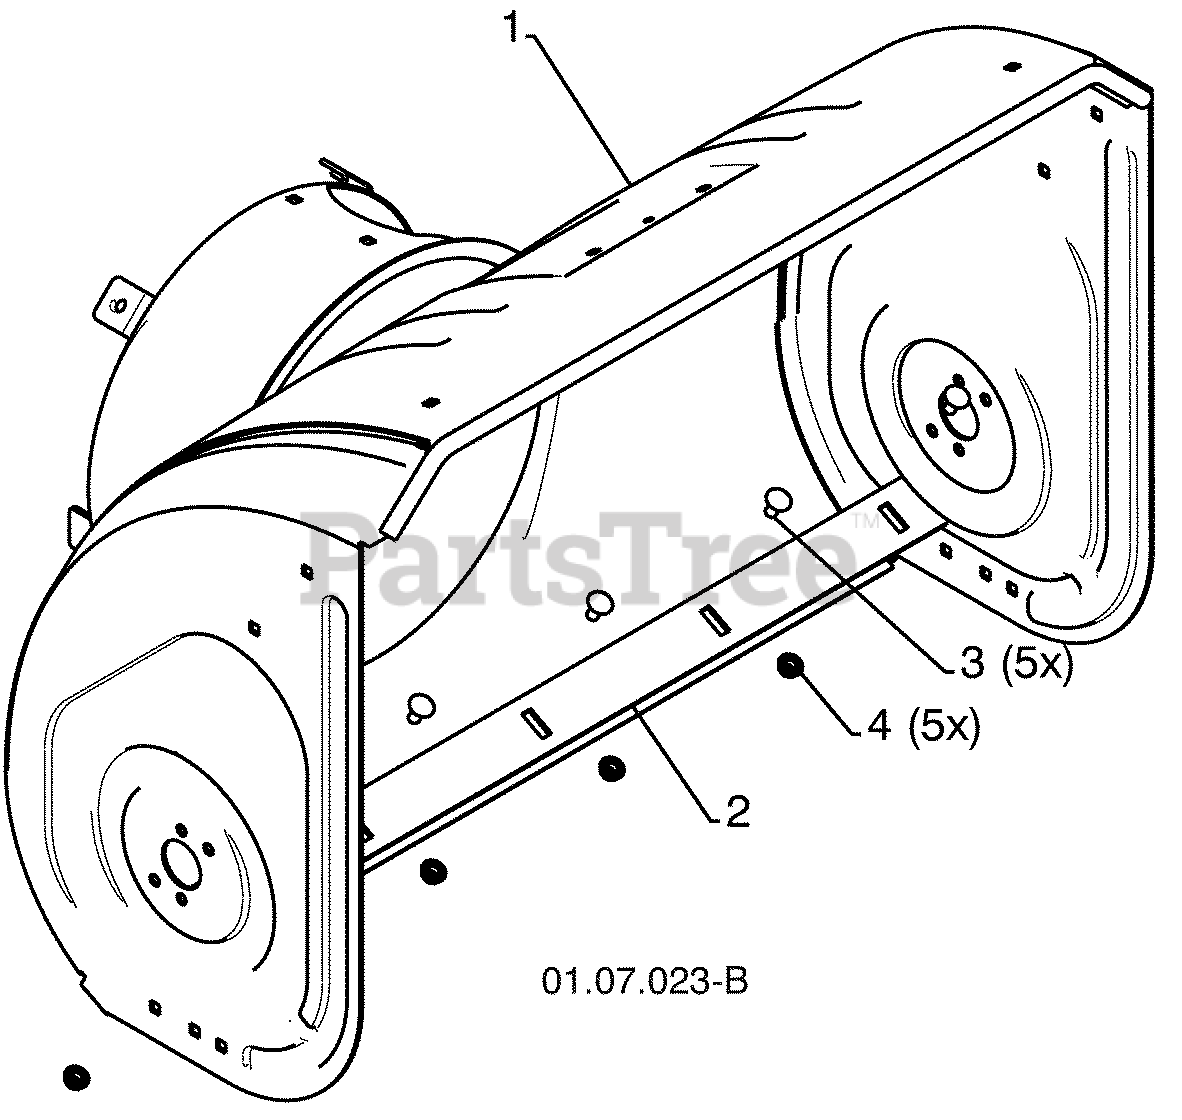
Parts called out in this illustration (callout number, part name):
1	AUGER HOUSING
2	SCRAPPER BAR
3	CARRIAGE BOLT 5/16-18 X .625
4	NUT 5/16-18
